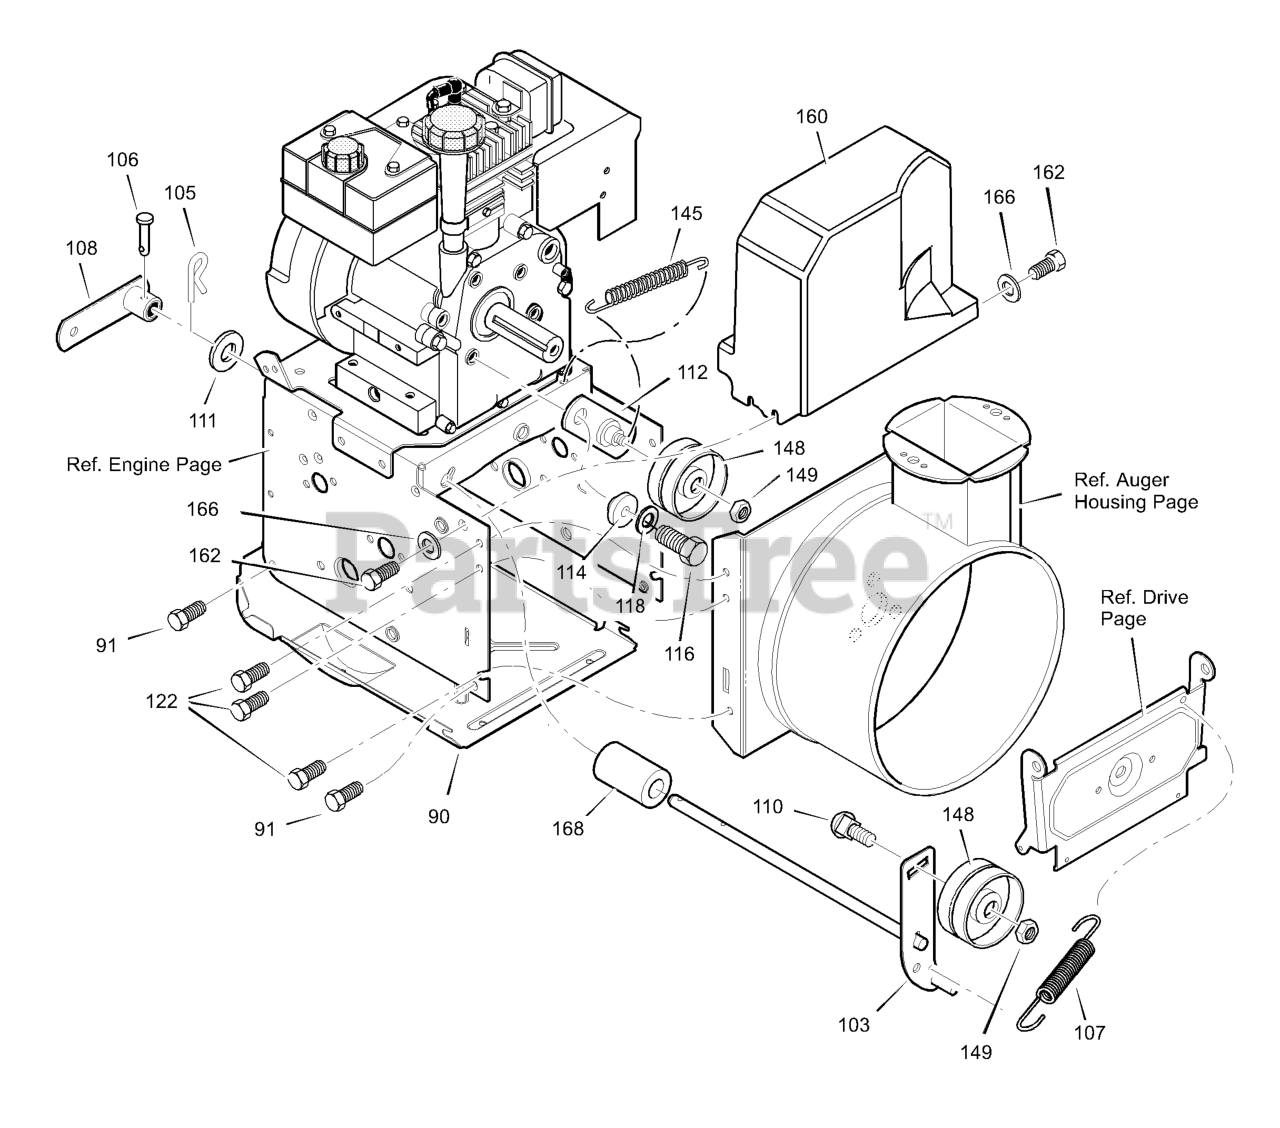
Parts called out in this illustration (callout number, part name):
90	COVER, BOTTOM
91	SCREW, 1/4-20X .63
103	IDLER ASSEMBLY, AUGER
105	PIN, HAIR .38DIAX1.64LG
106	PIN, CLEVIS 3/16" DIA
107	SPRING, TENSION
108	ASSY., SPRING ATTACH
110	BOLT, 3/8-16X1.25 CARR.
111	WASHER, FLAT
112	BRACKET ASSEMBLY, IDLER
114	BUSHING, IDLER BRACKET
116	SCREW 5/16-24 X 1.00
118	WASHER, SPLIT
122	SCREW, 5/16-18 x 0.50
122	SCREW, TAP 5/16-18 X .50
145	SPRING, IDLER TRACTION DRIVE
148	PULLEY, IDLER
149	NUT, JAM 3/8-16
160	COVER, BELT
162	SCREW, TAP 1/4-20 X .63
166	WASHER, FLAT
168	SPACER, AUGER BRACKET
